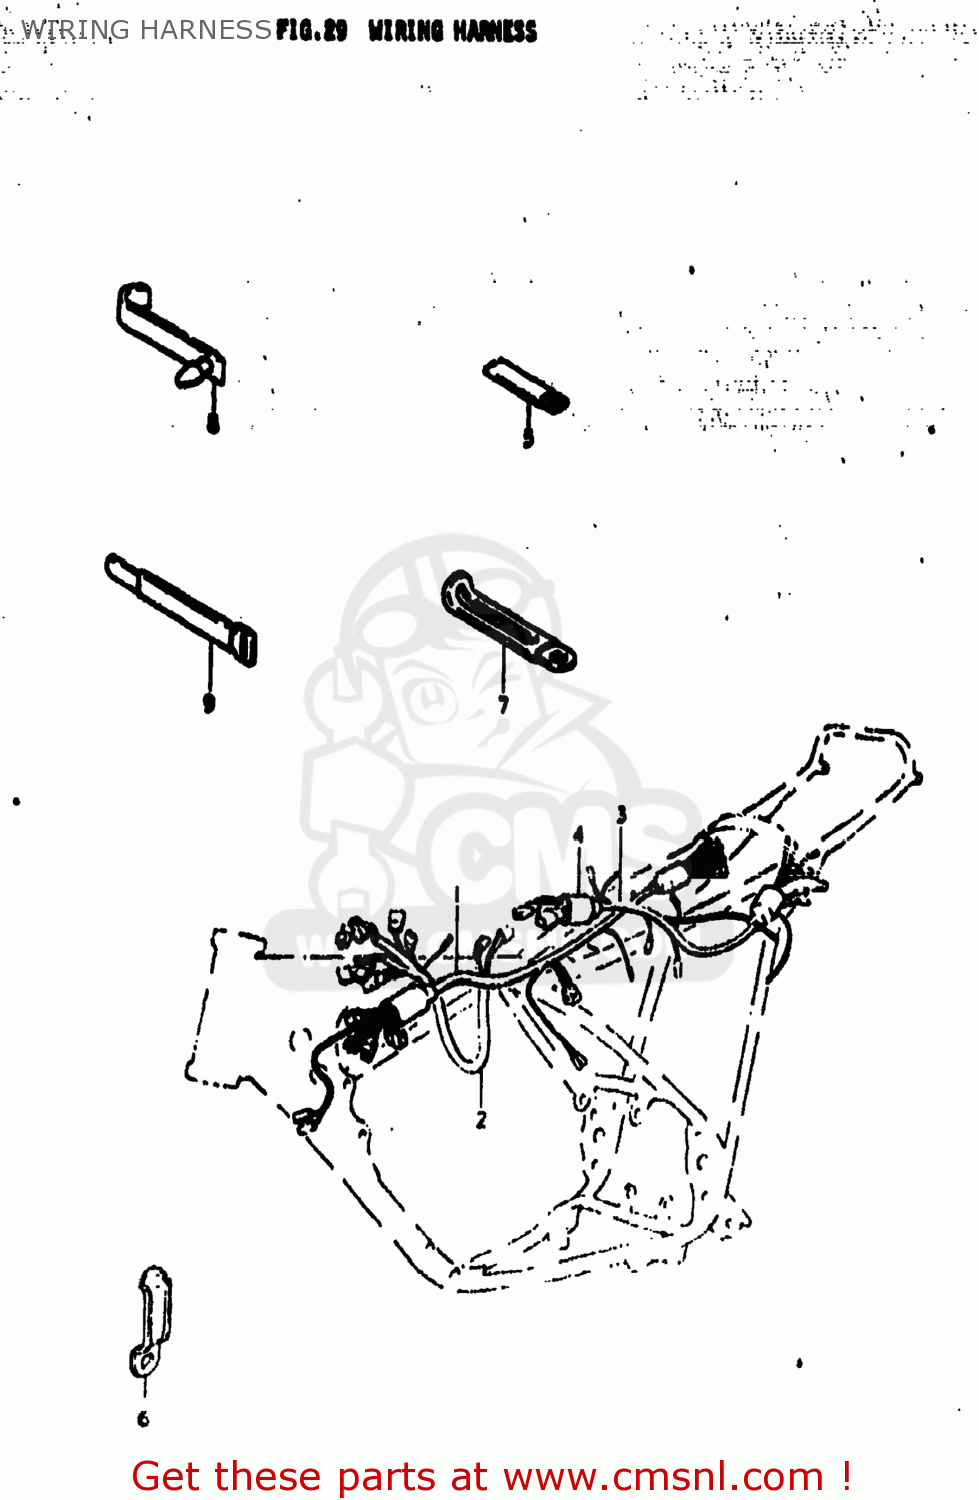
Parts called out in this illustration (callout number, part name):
1	HARNESS,WIRING
2	HARNESS,WIRING
3	HARNESS,WIRING NO.2
4	BOOT,WIRING HARNESS
5	CLAMP
6	CLAMP
7	CLAMP
8	BAND
9	CLAMP
